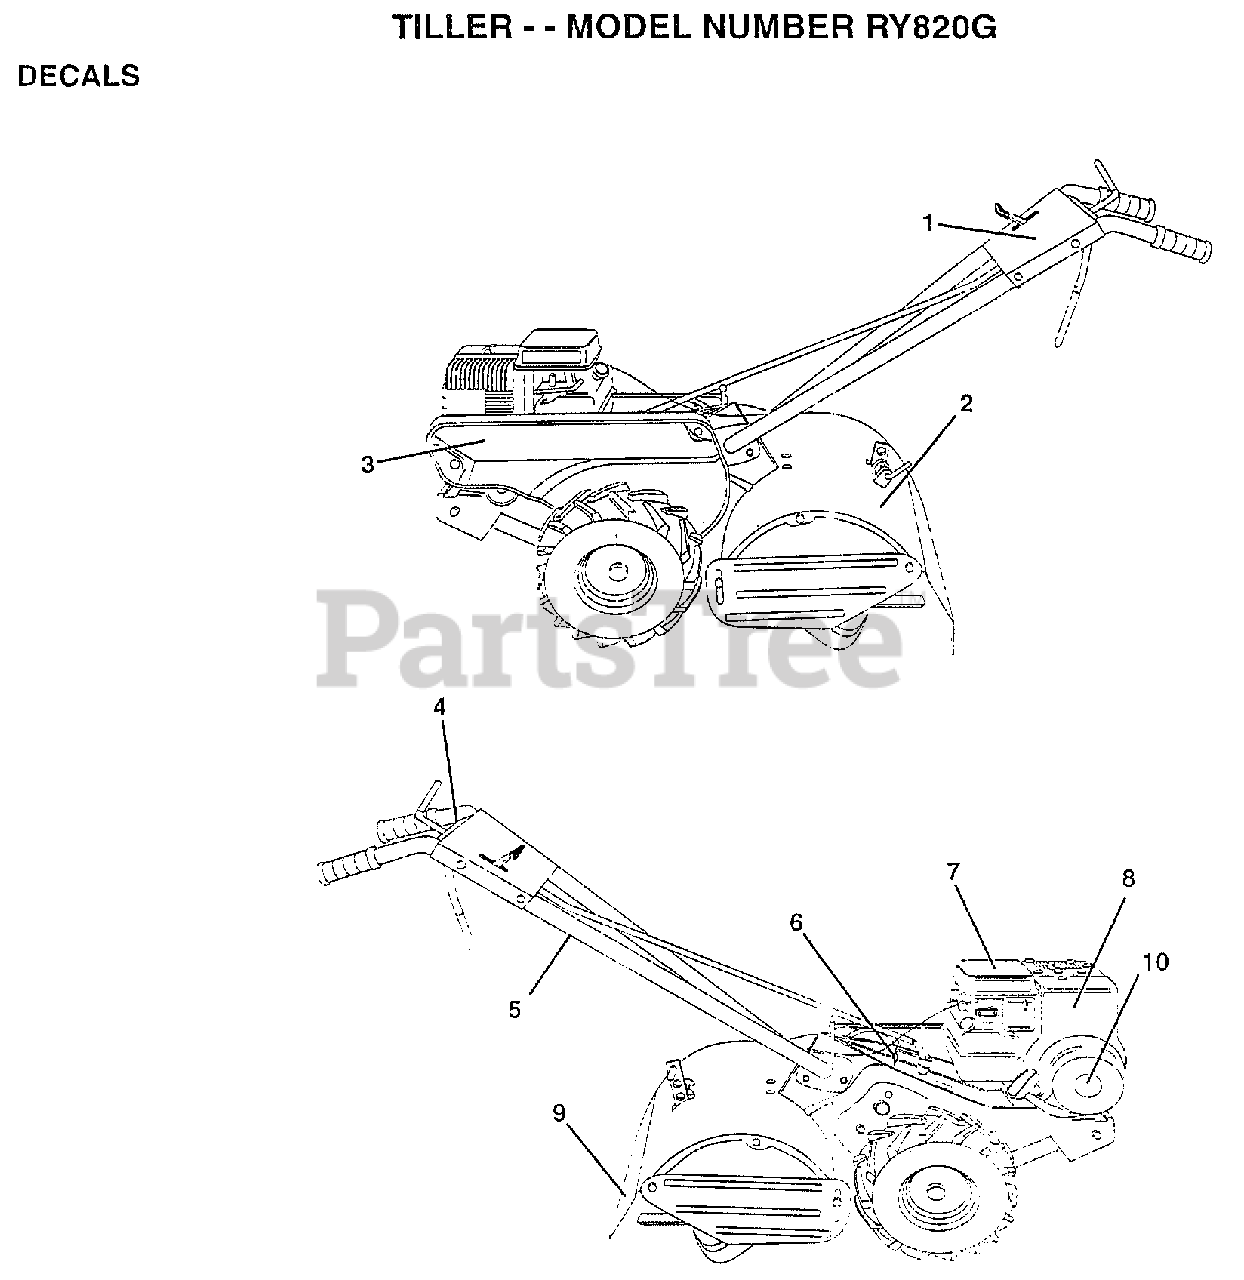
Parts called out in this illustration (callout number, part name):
3	DECAL, LOGO
5	DECAL TI
7	DECAL TI
8	DECAL, BRIGGS & STRATTON
10	DECAL, 5 HP
